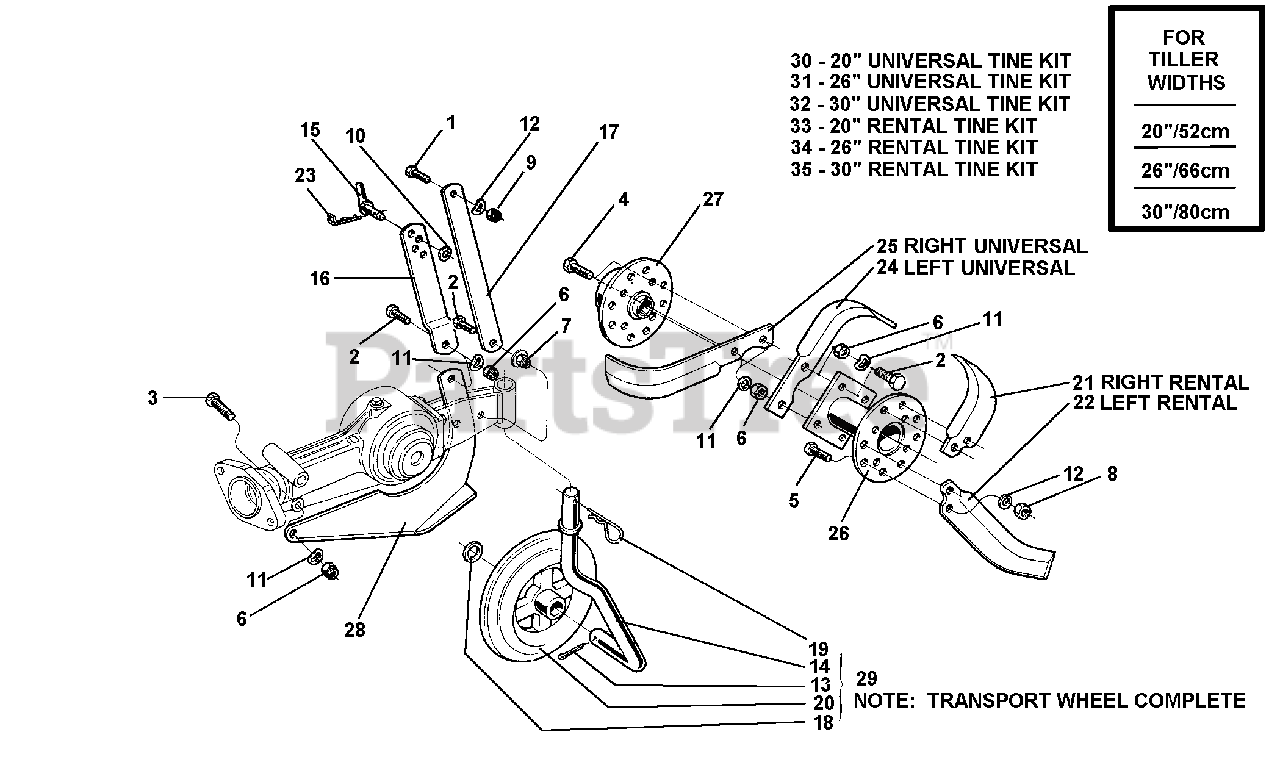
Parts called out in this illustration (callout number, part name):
1	SCREW TE M10 X 25
2	SCREW M8 X 25
3	SCREW TE M8 X 30
4	SCREW M8 X 35
5	SCREW TE M10 X 25 UNI 5739-8G
6	NUT, SELF LOCKING M8
8	NUT, SELF LOCKING M10
9	NUT, SELF LOCKING M10 LOW
10	WASHER P10.5 X 18
11	WASHER, LOCK 8.4
12	WASHER, LOCK 10.5
13	PIN, COTTER A 4 X 30 UNI 1336
14	WHEEL SUPPORT PIN
15	ADJUSTMENT PIN
16	ROTARY HOE KNIFE ROD
17	ROTARY HOE HOOD ROD
18	SPACER RING
20	RUBBER WHEEL D 22
21	RENTAL RIGHT KNIFE
22	RENTAL LEFT KNIFE
24	UNIVERSAL LEFT KNIFE
25	UNIVERSAL RIGHT KNIFE
26	SPACER KNIVES
27	BLADE HOLDER FLANGE D 25
28	CENTRAL KNIFE
29	TRANSPORT WHEEL ASSEMBLY
30	20" UNIVERSAL TINE KIT
31	26" UNIVERSAL TINE KIT
32	30" UNIVERSAL TINE KIT
33	20" RENTAL TINE KIT
34	26" RENTAL TINE KIT
35	30" RENTAL TINE KIT
